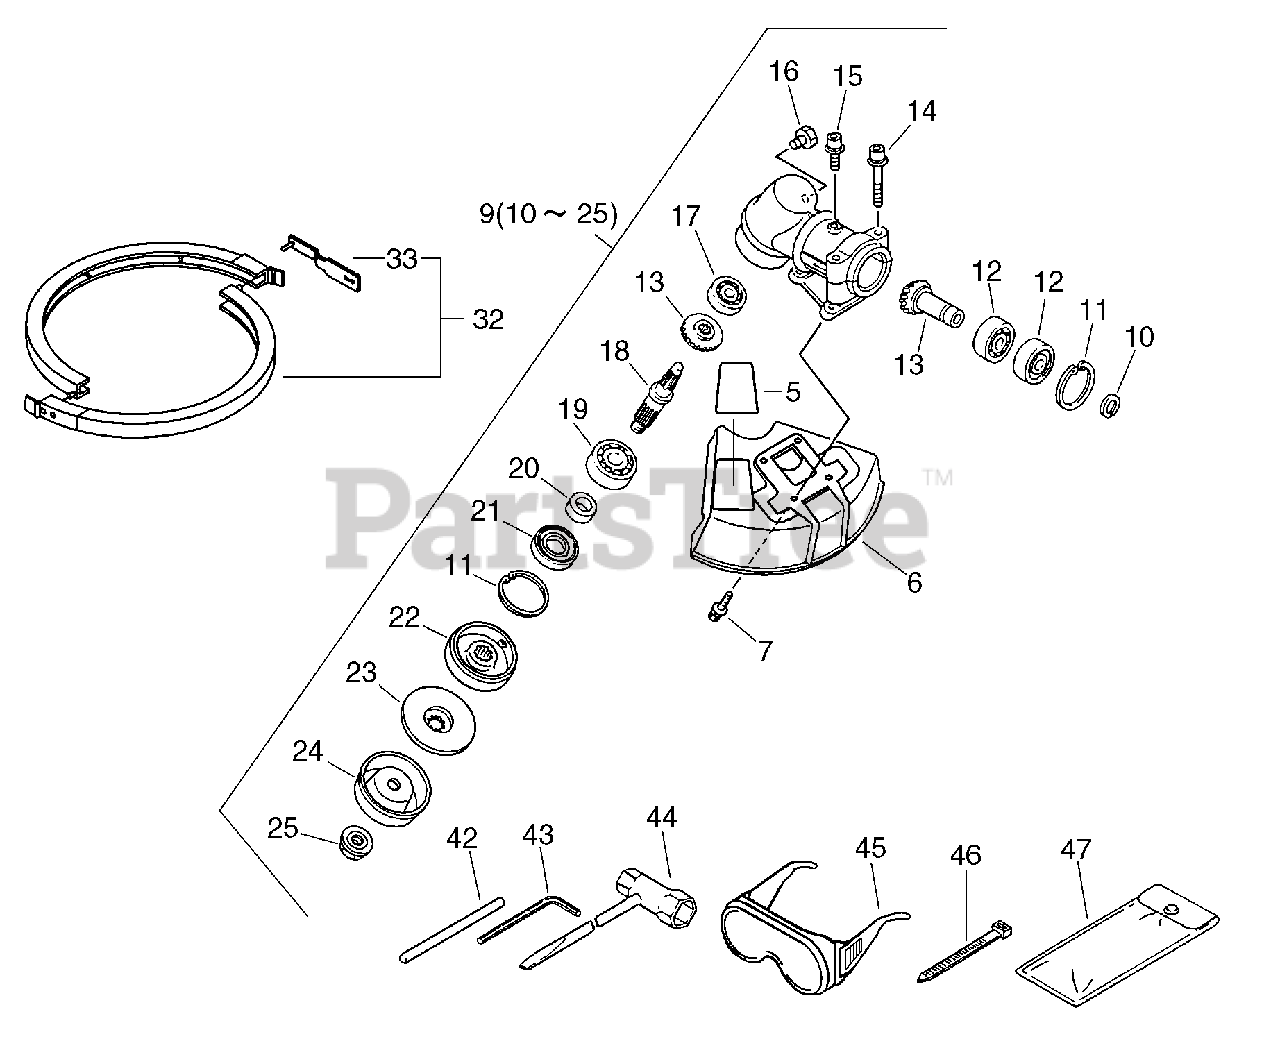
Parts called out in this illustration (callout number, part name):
5	LABEL - CAUTION
6	SHIELD, DEBRIS
7	SCREW - 5X20
9	GEAR CASE ASSY
10	RING, RETAINING - 15
11	RING, RETAINING - 35
12	BEARING, BALL - 6202
13	GEAR SET
14	SCREW - 5X35
15	SCREW - 5X14
16	BOLT - 8X8
17	BEARING, BALL - 6001
18	GEAR - SHAFT
19	BEARING, BALL - 6202Z
20	SPACER, OILSEAL
21	SEAL, OIL
22	ADAPTOR, BLADE - UPPER
23	ADAPTOR, BLADE - LOWER
24	PLATE, CUP
32	COVER, BLADE - 9" (22cm)
42	LOCKING TOOL
43	HEX KEY - 4mm
44	T-WRENCH - 17X19mm
45	GOGGLES
46	TIE, CABLE - SMALL
47	BAG, TOOL
